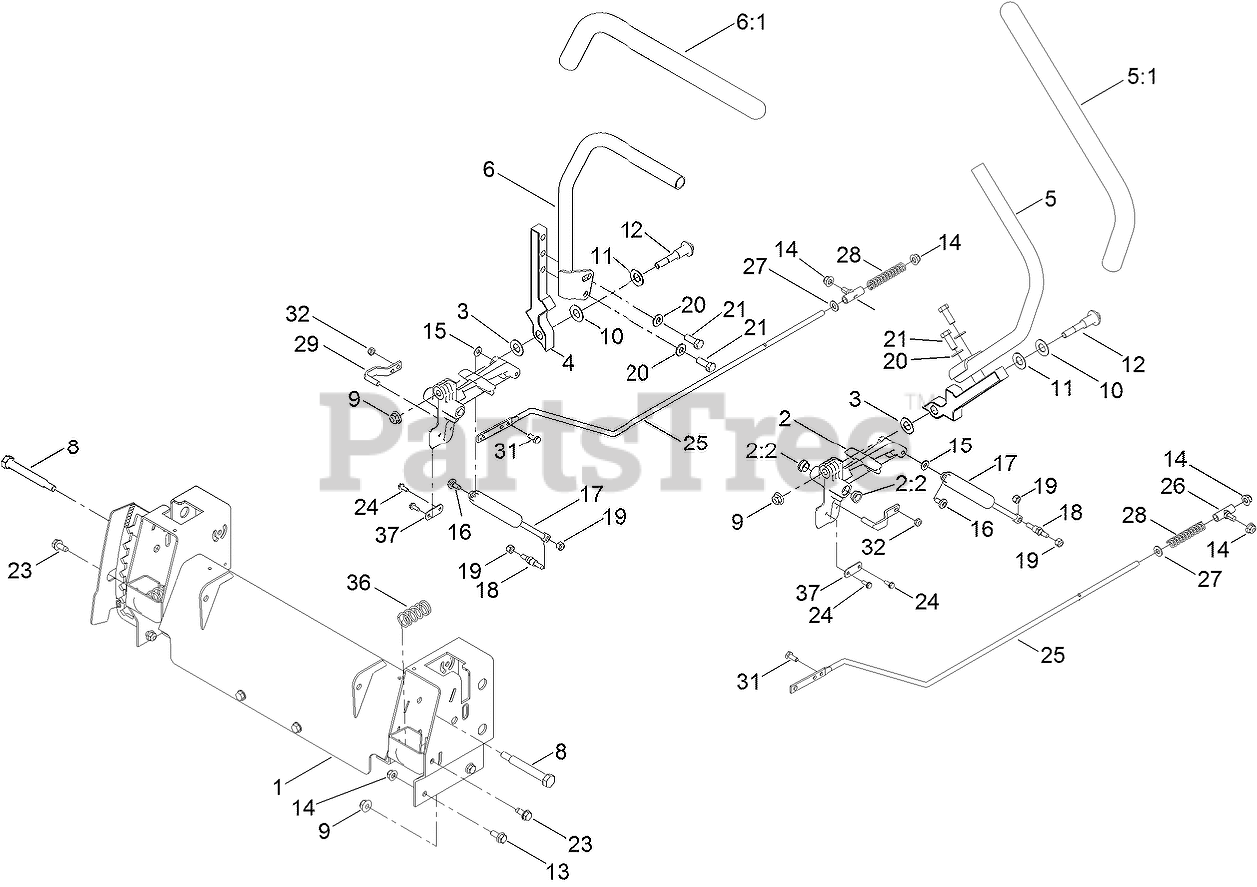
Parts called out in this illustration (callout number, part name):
1	CONTROL BOX ASM
2	ACTUATOR ARM ASM
2:2	BUSHING-FLANGE
3	WASHER-NYLON
4	ARM-CONTROL
5	HANDLE-CONTROL, LH
6	HANDLE-CONTROL, RH
8	BOLT-PIVOT
9	NUT-HF, NI
10	WASHER
11	WASHER-BELLEVILLE
12	BOLT-PIVOT
13	SCREW-HHF
14	NUT-HF, NI
15	WASHER
16	SCREW-SHOULDER
17	DAMPER
18	STUD-DAMPER
19	NUT-LOCK, NI
20	WASHER-FLAT
21	SCREW-HH
23	SCREW-HWHTF
24	SCREW-TAPTITE
25	ROD-HYDRO
26	MOUNT-ROD, HYDRO
27	WASHER-PLAIN
28	SPRING-RETURN, NEUTRAL
29	PIN-ROD, HYDRO
31	SCREW-HH
32	NUT-LOCK, NI
36	SPRING-RETURN
37	PLATE-STOP, HYDRO
